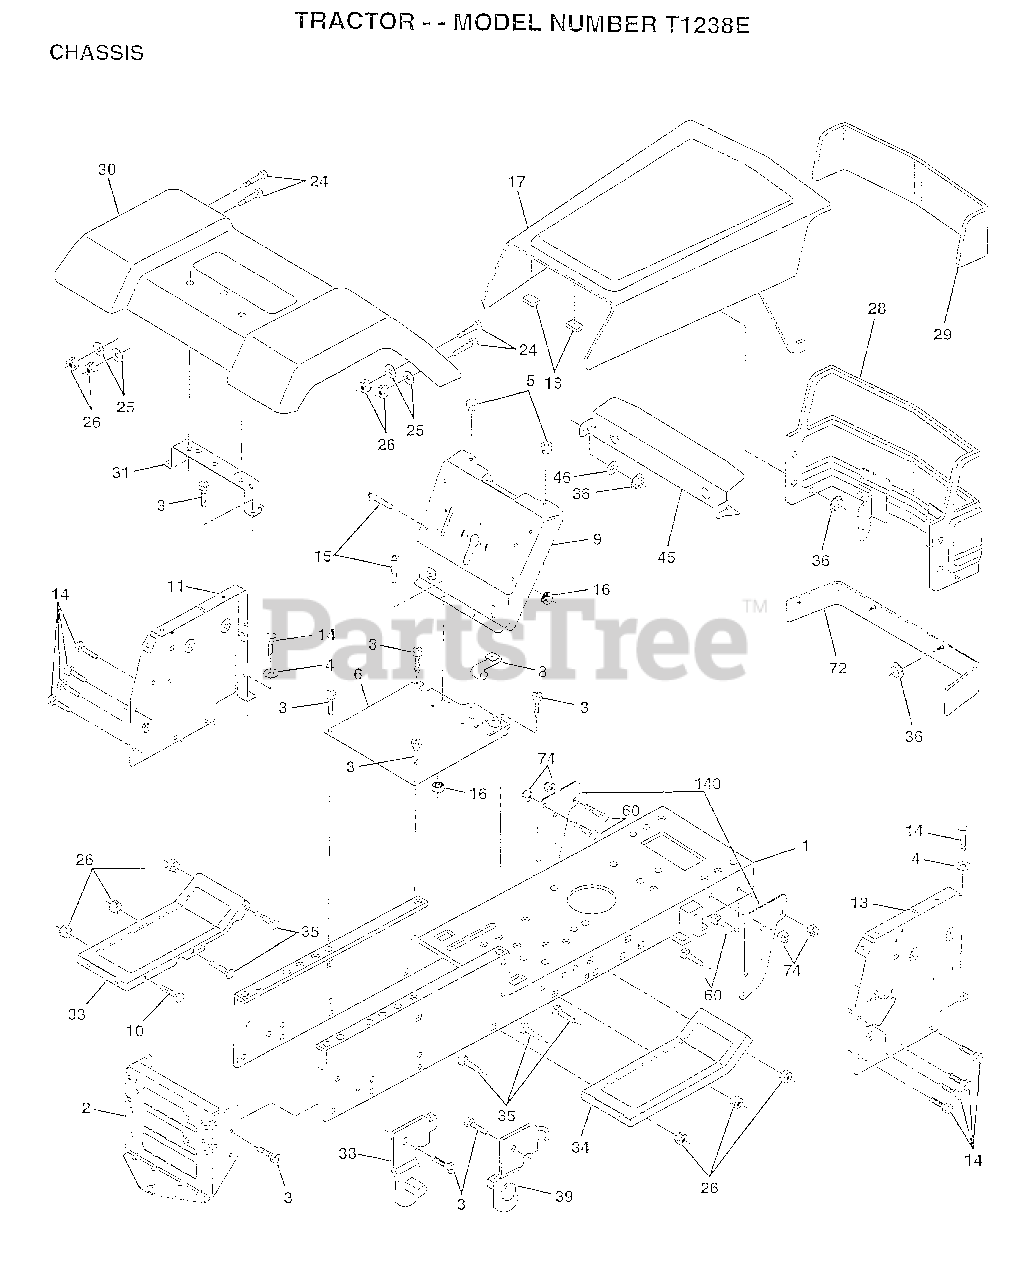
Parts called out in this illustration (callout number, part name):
1	CHASSIS WLDMT 11G
3	SCREW
4	WASHER
8	"CLIP,INSULATOR"
9	DASH.SLKSC.LT.1PC
11	PANEL.DASH.LH.
14	SCREW LT
15	SCREW
17	HOOD.W/SD.PNLS.LT
24	BOLT
25	WASHER
26	NUT
28	GRILLE.RALLY.BAR.
29	LENS SERVICE KIT
31	BRKT FENDER
33	FOOTREST.LH.PERF.
34	FOOTREST.RH.PERF.
35	BOLT
36	PAL NUT LT
38	BRACKET ASM LH
39	BRACKET ASM RH
46	RETAINER
60	BOLT
72	STRAP.GRILLE.PNT.
